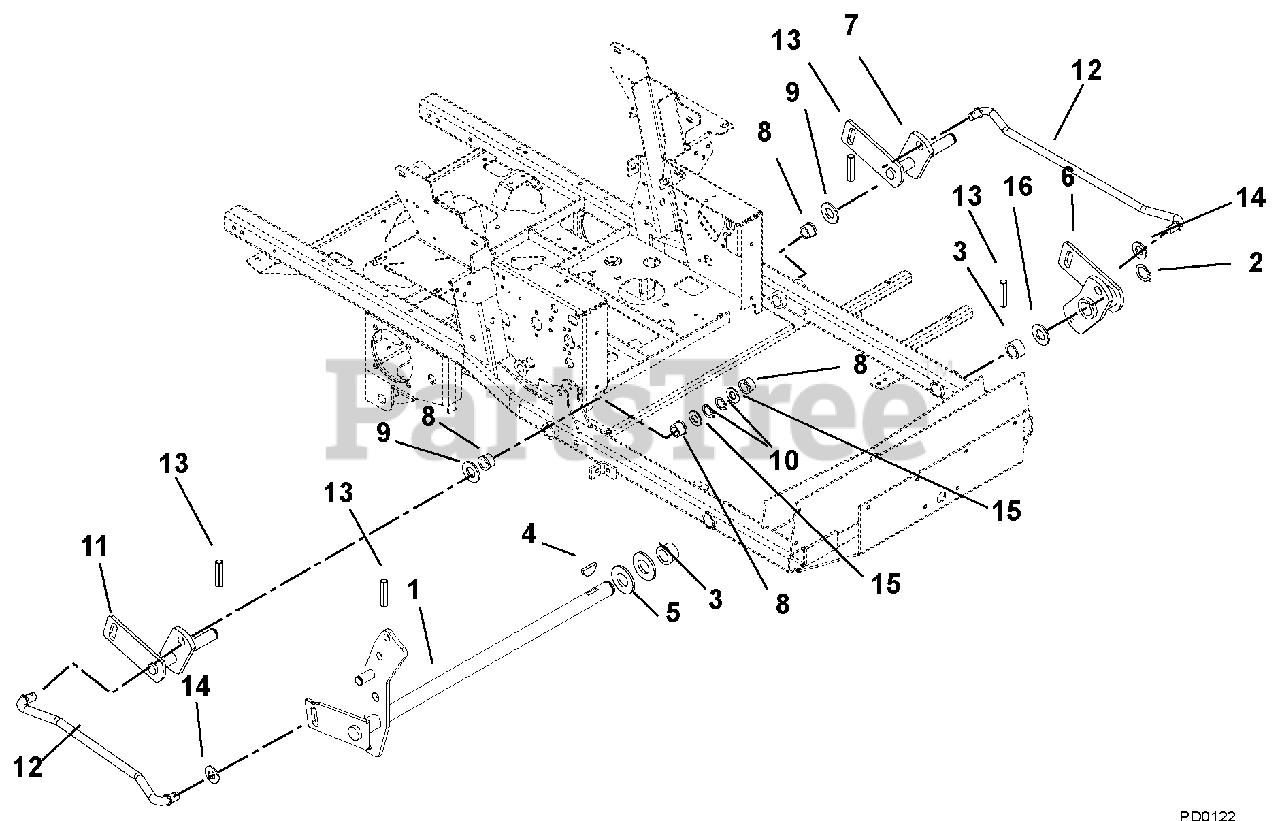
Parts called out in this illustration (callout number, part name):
1	Lift, Hydraulic Mower
2	Ring, Retaining External 1.00 x .078
3	Bushing, 1.00 x 1.12 x .75 x 1.375
4	Key, Woodruff .25 x 1.00
5	Washer, Flat Steel 1.062 x 2.00 x .134
6	Weldment, Lift Arm Front
7	Weldment, Rear Lift Arm Left Hand
8	Bushing, Flange Nylon .762 x 1.00 x .58 x 1.48
9	Washer, Hardened Steel .758 x 1.23 x .031
10	Ring, Retaining External .689 x .077
11	Weldment, Right Hand Rear Lift Arm
12	Rod, Lift Assist
13	Pin, Roll .250 x 1.25 Stainless Steel
14	Washer, Flat Steel .630 x 1.25 x .062
15	Washer, Flat Steel .812 x 1.50 x .135
16	Washer, Hardened Thrust 1.00 x 1.55 x .03
